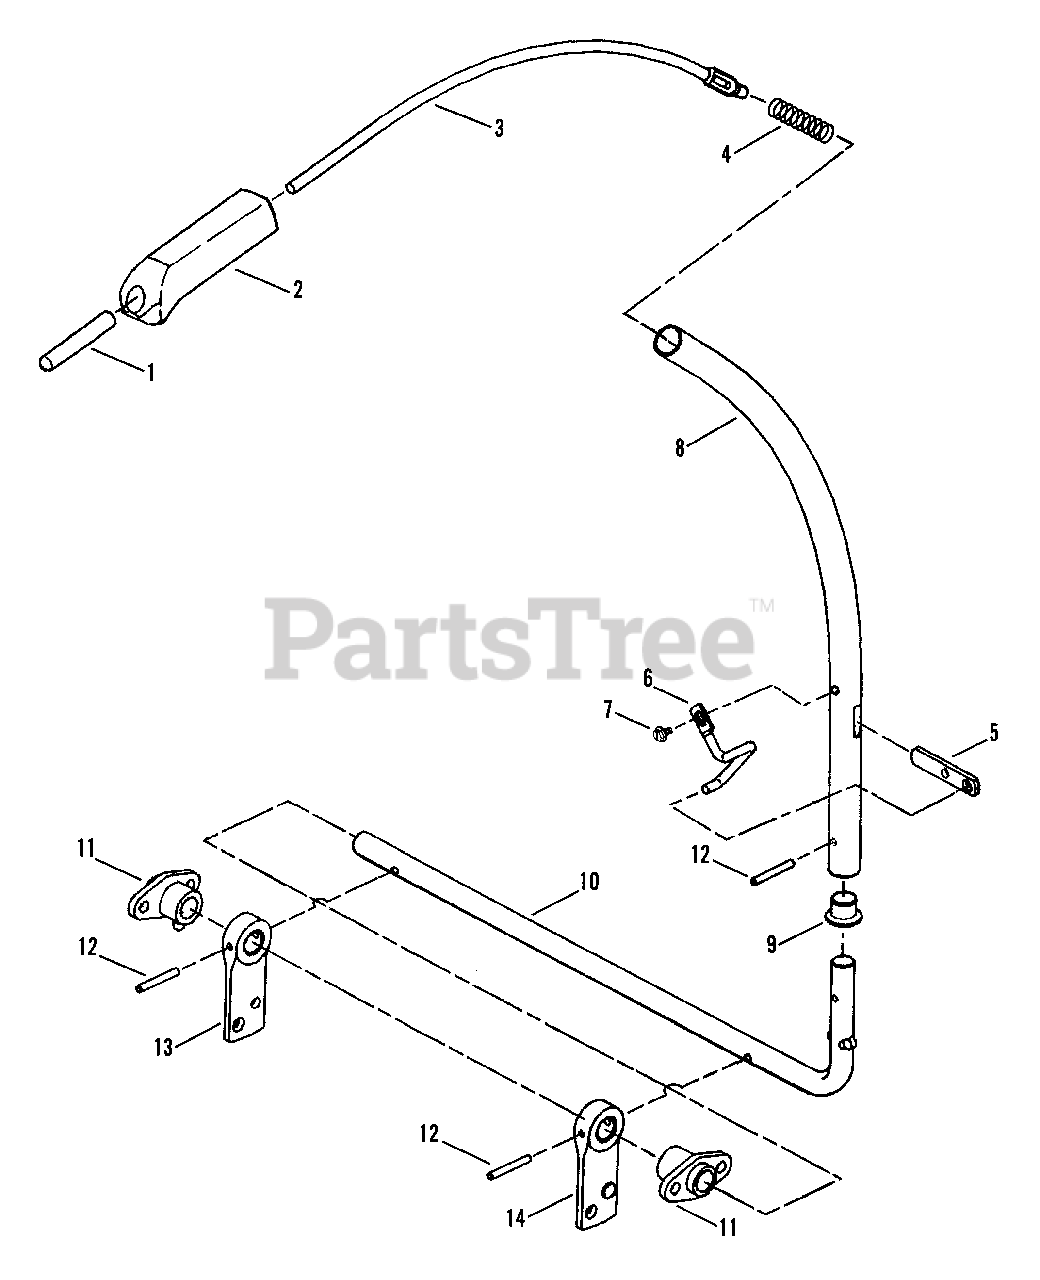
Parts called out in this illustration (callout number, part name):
1	GRIP, 5/16 x 2-1/2" Vinyl
2	GRIP, Brake/Clutch Handle
3	ROD, Park Brake
4	SPRING, Brake/Clutch Release
5	ARM, Brake/Clutch Lever
6	PIVOT, Brake/Clutch Lever
7	SCREW, 1/4-20 x 3/8" Slotted Hex Washer Head, Self-Tapping
8	TUBE, Brake/Clutch Lever
9	BUSHING, Nylon
10	ROD, Brake/Clutch
11	PIVOT, Foot Shaft Assembly
12	ROLL-PIN, 3/16 x 1-1/2"
13	ARM, Brake/Clutch
14	ARM, Brake/Clutch
